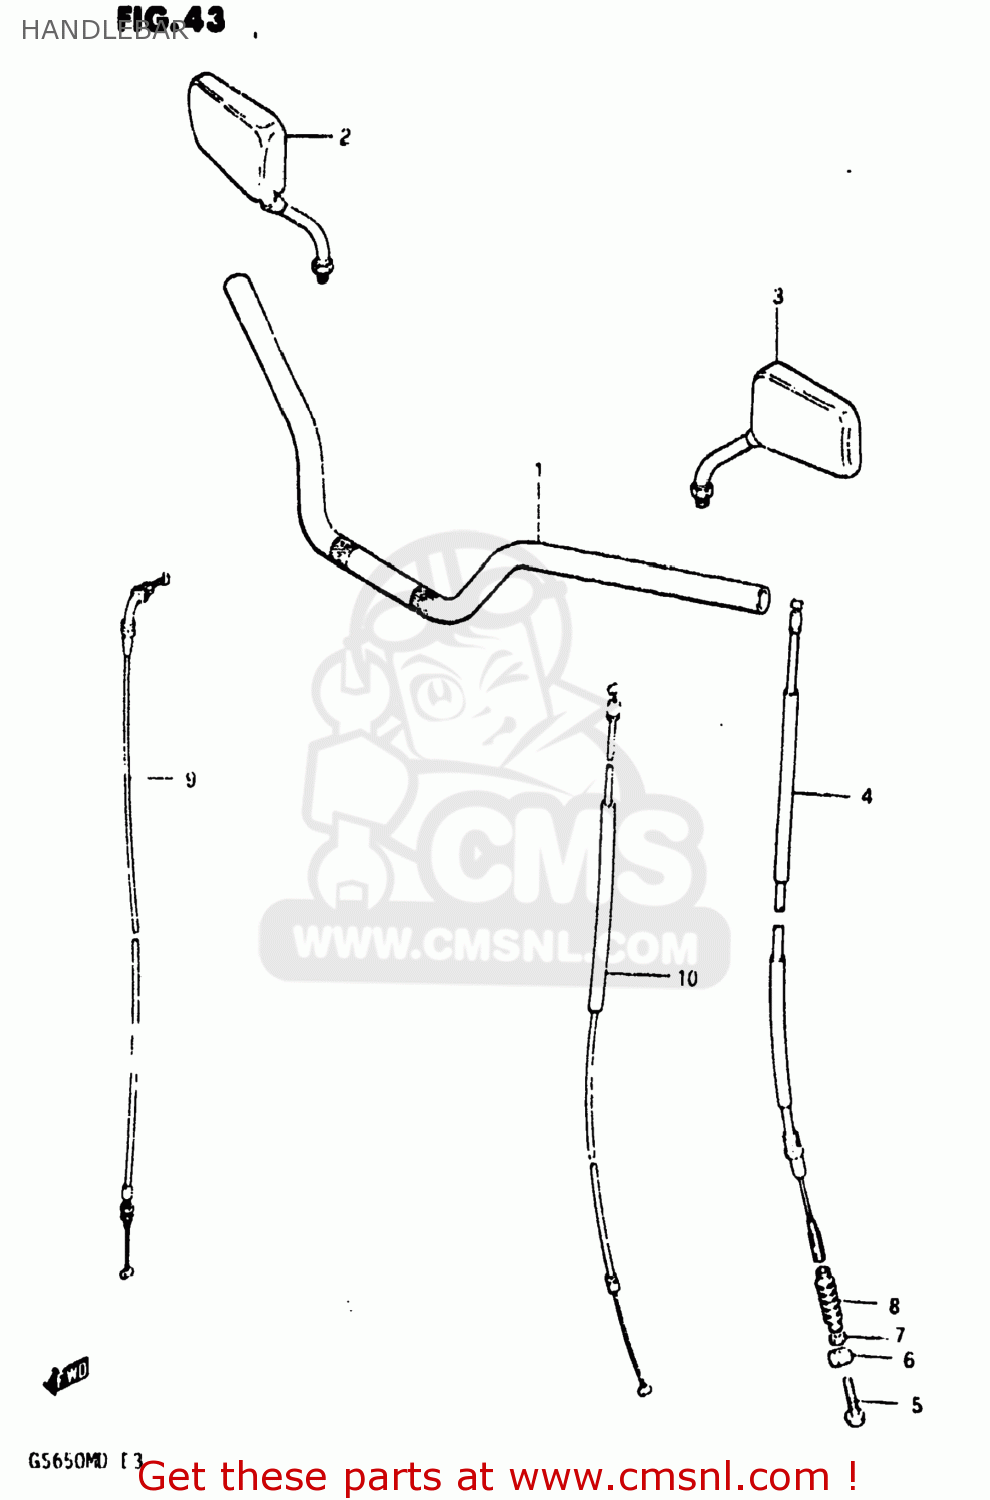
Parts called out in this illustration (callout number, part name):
1	HANDLEBAR
2	MIRROR ASSEMBLY,REAR VIEW
3	MIRROR ASSEMBLY,REAR VIEW
4	CABLE ASSEMBLY,CLUTCH
5	SCREW
6	PIN
7	NUT
8	DUST SEAL
9	CABLE ASSEMBLY,THROTTLE
10	CABLE COMP,STARTER
